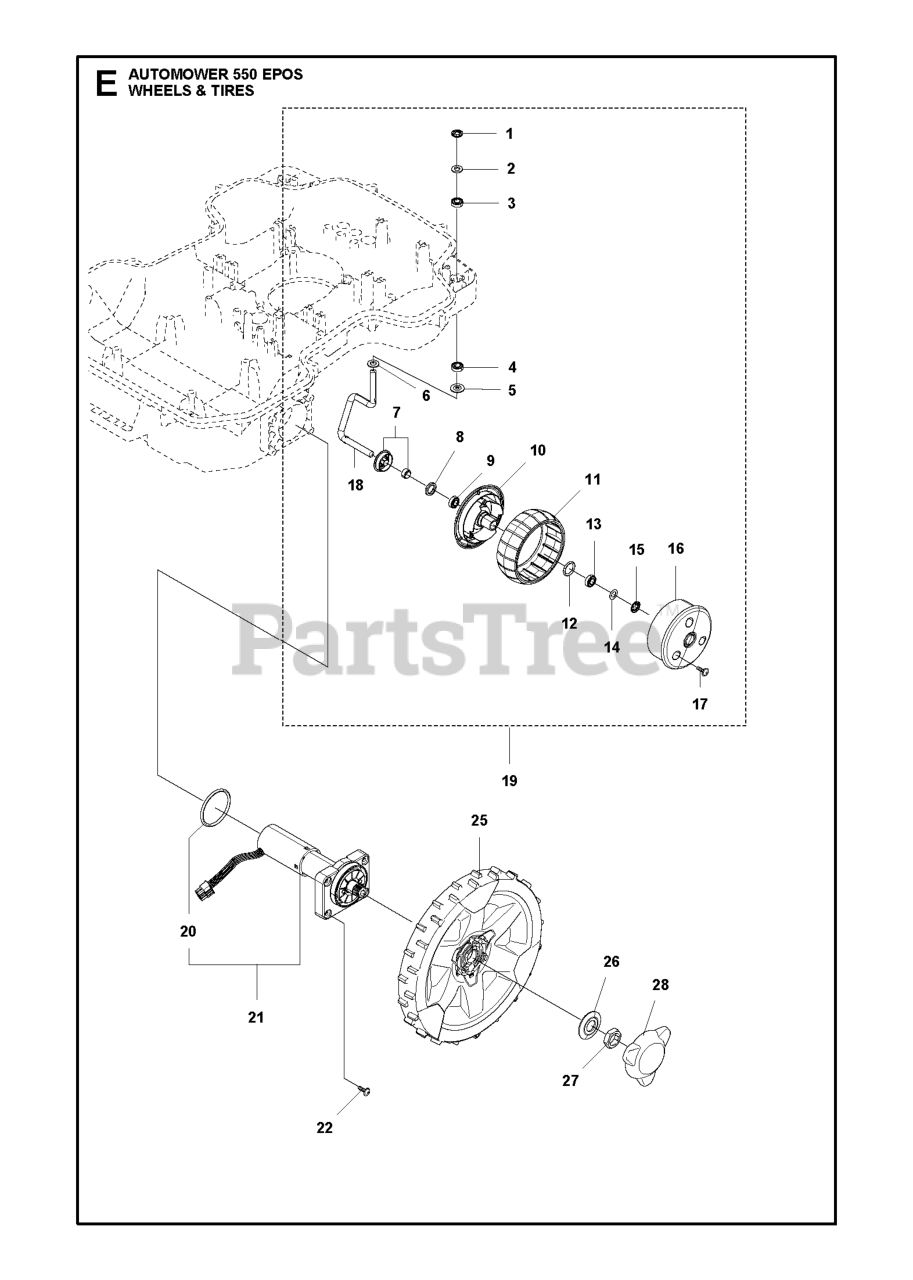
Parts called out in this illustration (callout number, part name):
1	LOCKWASHER PUSH-ON TYPE P 8 BV
2	WASHER DIN 988 13X8X0.5
3	BALL BEARING SINGLE ROW S688
4	BALL BEARING SINGLE ROW S688
5	WASHER FRONT WHEEL CENTER HOLE
6	WASHER DIN 988 13X8X0.5
7	SHIELD KIT
8	SEALING 12X18X3
9	BALL BEARING SINGLE ROW S688
10	WHEEL FRONT WHEEL INSIDE
11	WHEEL RUBBER TYRE
12	O-RING 2,62X15,54
13	BALL BEARING SINGLE ROW S688
14	WASHER DIN 988 13X8X0.5
15	LOCKWASHER PUSH-ON TYPE P 8 BV
16	WHEEL FRONT WHEEL OUTSIDE
17	SCREW 14MM
18	SPINDLE SPINDLE FRONT WHEEL RI
19	Wheels
20	O-RING LIGHT GREY
21	Motor
22	SCREW ITXPANT
25	WHEEL ASSY D249 HVA LIGHT GREY
26	WASHER WASHER REAR WHEEL 16X40
27	HEXAGON THIN NUT
28	HUB CAP REAR WHEEL NO CENTER P
